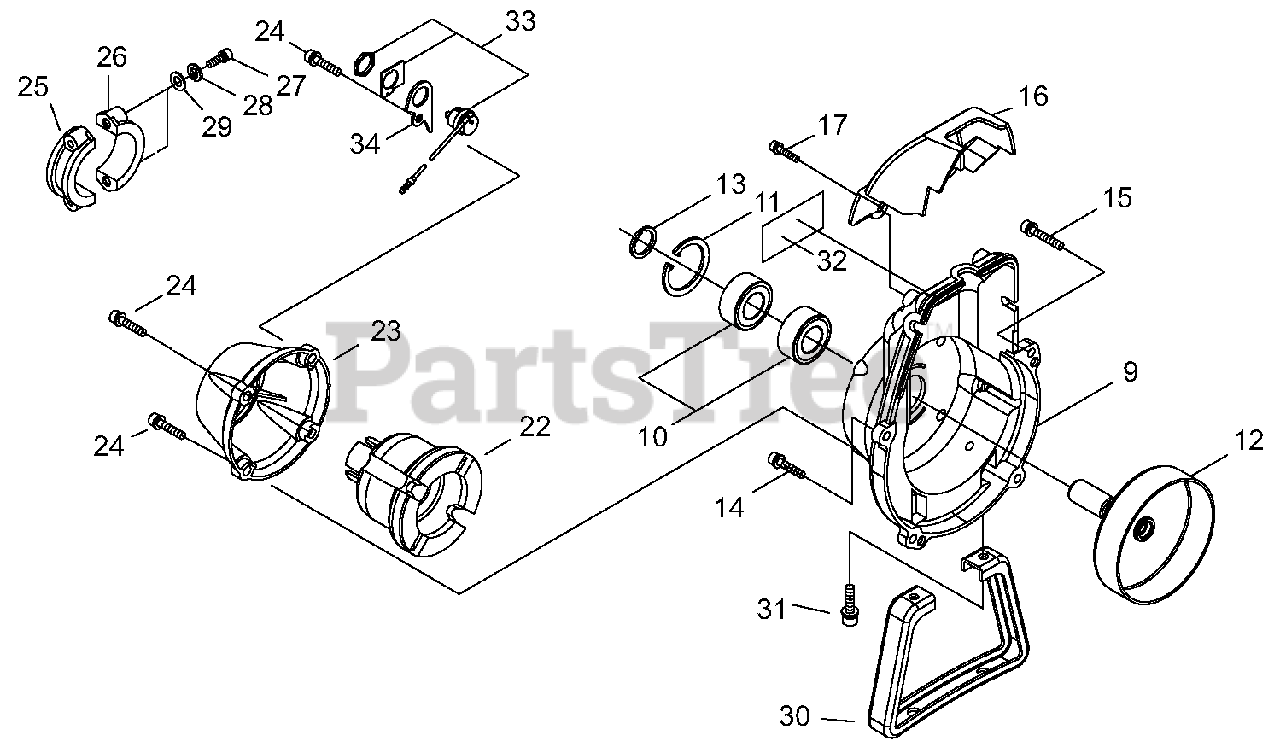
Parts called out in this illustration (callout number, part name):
9	COVER, FAN
10	BEARING, BALL 6002 DDU
11	RING, SNAP Ø32
12	DRUM ASSY, CLUTCH
13	RING, SNAP
14	BOLT M5×20
15	BOLT M5×30
16	GUARD, TOP
17	BOLT M4×16
22	CUSHION, AV
23	CAP, CUSHION
24	BOLT M5×20
25	CLAMP - A
26	CLAMP - B
27	BOLT 5×25
28	WASHER, SPRING 5
29	WASHER, FLAT 5.5×10×0.8
30	STAND
31	BOLT M5×16
32	LABEL - MODEL B45LA
33	SWITCH, ON-OFF
34	BRACKET
